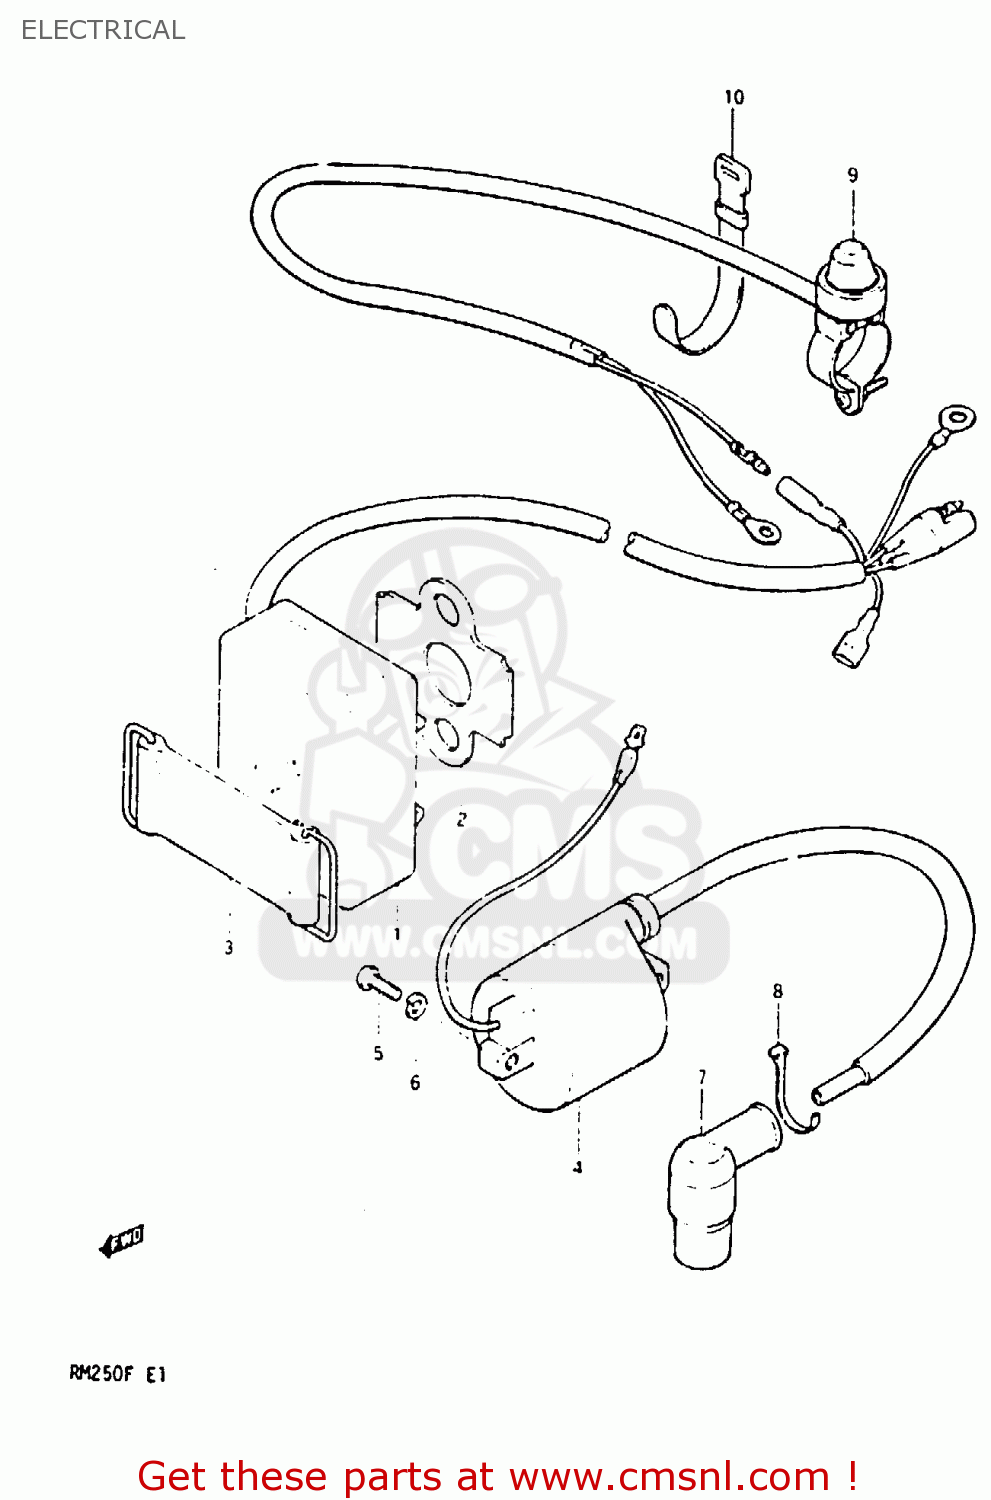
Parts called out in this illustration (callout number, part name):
1	CDI UNIT
2	PROTECTOR,CDI UNIT
3	BAND
4	COIL ASSEMBLY,IGNITION
5	SCREW
6	LOCK WASHER
7	CAP,SPARK PLUG
8	CLAMP
9	SWITCH ASSEMBLY
10	CLAMP(L:120)
